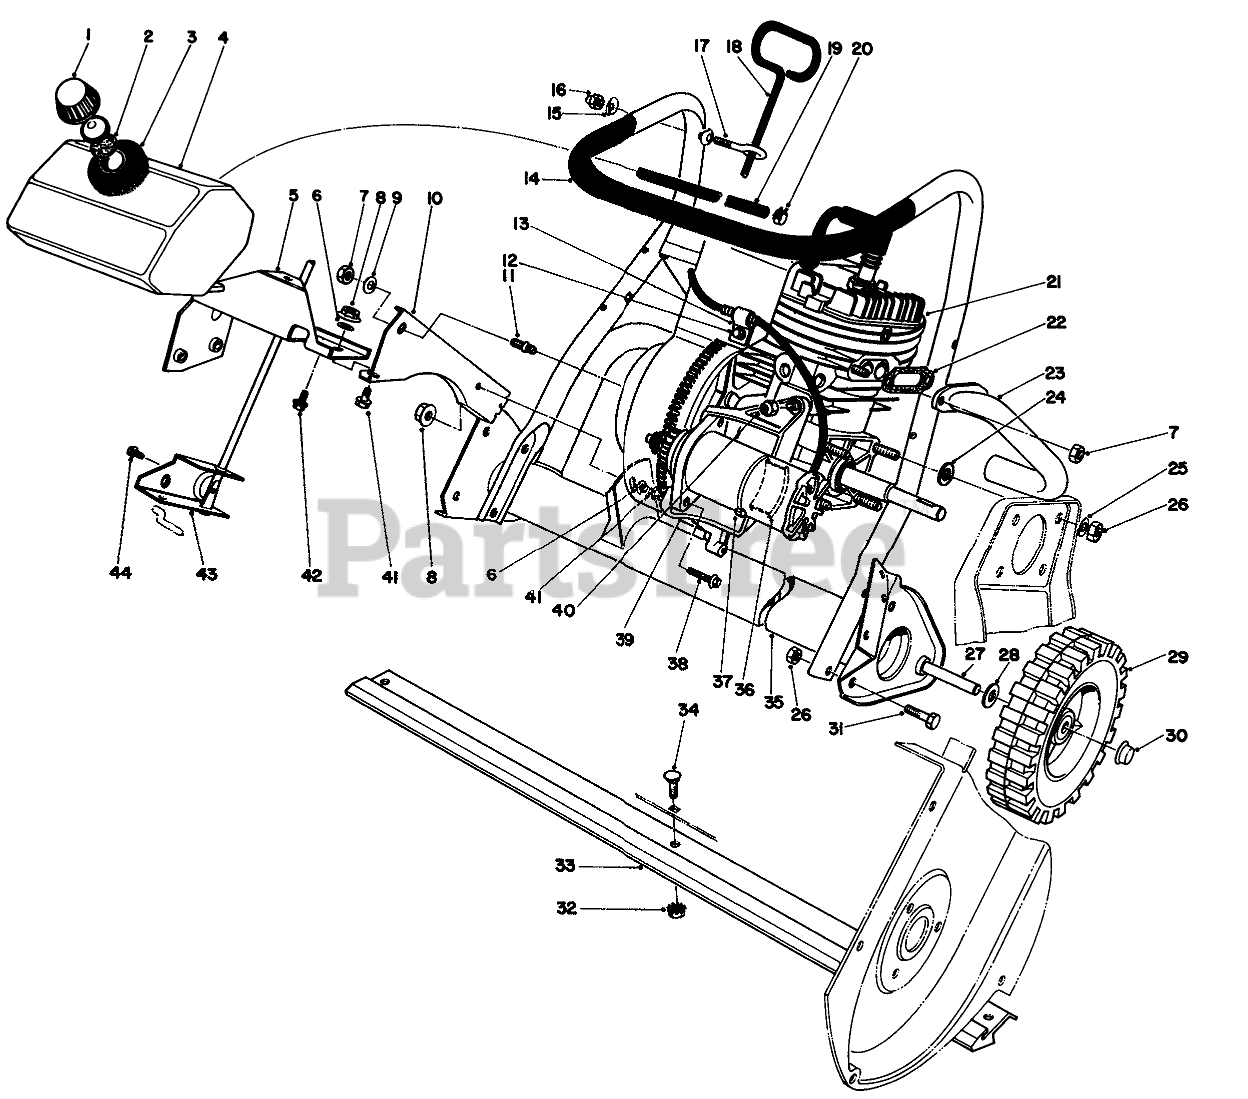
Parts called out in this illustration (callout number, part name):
1	GAS CAP ASM
2	GAS CAP GASKET
3	FOAM PAD
4	GAS TANK
5	Support-Gas Tank
6	WASHER-LOCK
7	NUT-LOCK, CONE
9	GRILLE HINGE SPACER
10	ENGINE SUPPORT
12	SCREW-HWH
13	CABLE CLAMP
14	Lower Handle
15	WASHER
16	NUT-CAP
17	EYEBOLT
18	ADJ ROD ASM
19	GasLine
20	Clamp
21	Engine
22	EXHAUST GASKET
23	EXHAUST PIPE
24	WASHER-FLAT
25	WASHER-PLAIN
26	NUT-LOCK, NI
28	WASHER-FLAT
29	WHEEL
30	RETAINER-PUSH ON
31	SCREW-HH
32	NUT-KEPS
33	SCRAPER
34	BUTTON HD CARR SCR
35	MUFFLER ASSEMBLY
36	RR MOTOR SUPPORT
37	TIE-CABLE
38	SCREW-FLOW, TAPTITE
39	MOTOR MTG BRKT
40	NUT-LOCK, NI
41	5/16-18X.62 WHIZLOK SCR
42	SCREW
43	VANE ADJ BRKT
44	SCREW
